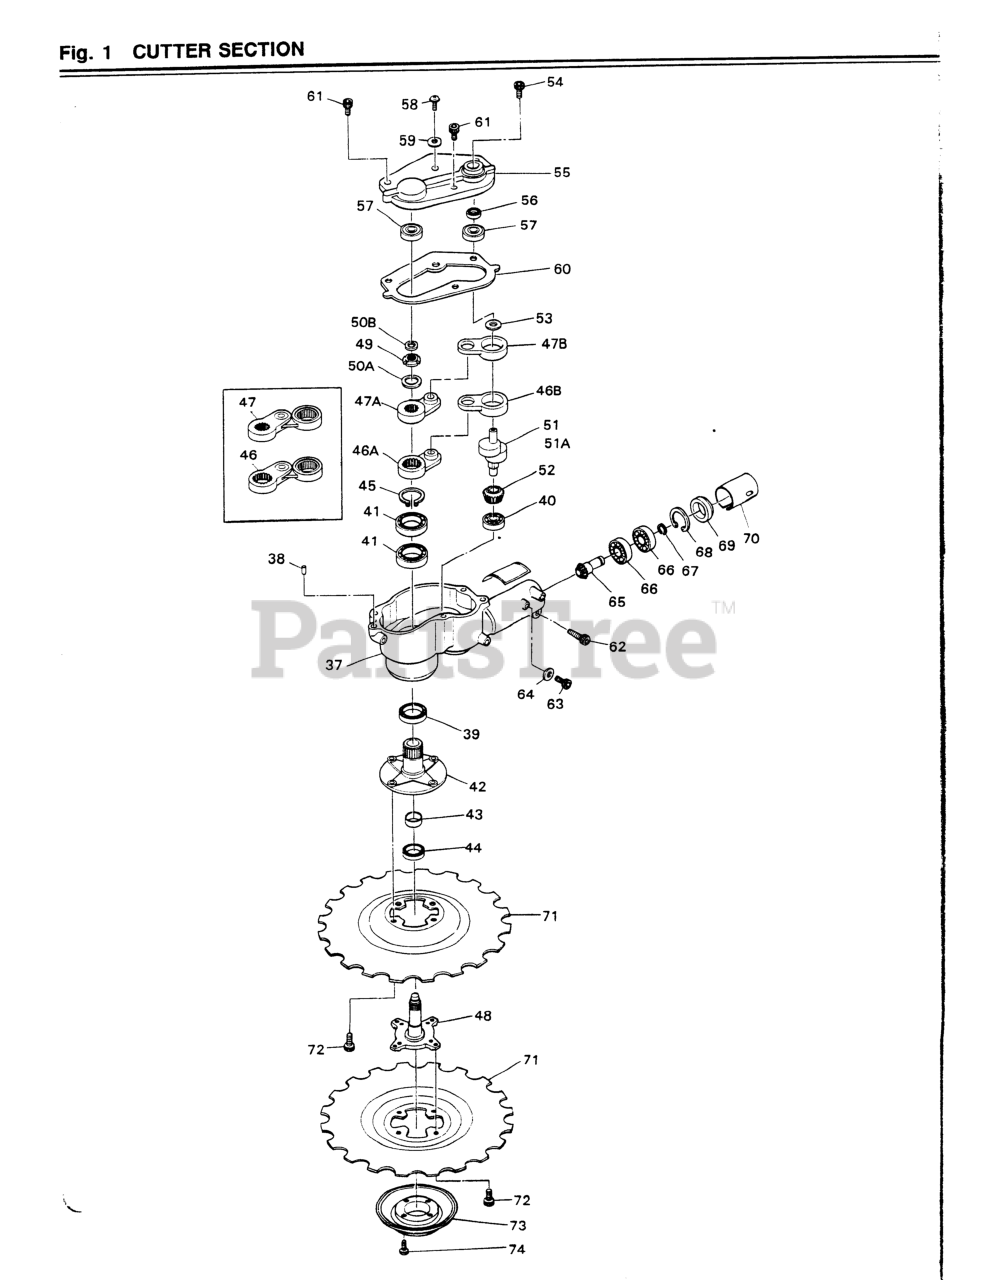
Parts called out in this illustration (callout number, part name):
38	PIN, DOWELL
39	SEAL, OIL
41	BEARING
42	SHAFT, OUTER-C
43	BUSHING
44	SEAL, OIL
45	RING, SNAP, M20 x 1.2
46	LINK-L-C
48	SHAFT, INNER
50A	SHIM, 0.3t
51A	CRANKSHAFT (RPLS -13710)
52	GEAR
53	WASHER, M8 x 1.2
54	BOLT
56	SEAL, OIL
57	BEARING (RPLS. T4001-31340)
58	SCREW, M6 x 10
59	GASKET
60	GASKET
61	BOLT, M5 x 20
62	BOLT, M5 X 25
63	BOLT, M5 x 14
65	PINION
66	BEARING (RPLS T3403-13510)
67	RING, SNAP
68	RING, SNAP, M26 X 1.2
69	PACKING
72	BOLT, M6 x 8
74	SCREW, M5 X 8
NI	SHIM, 0.2T
